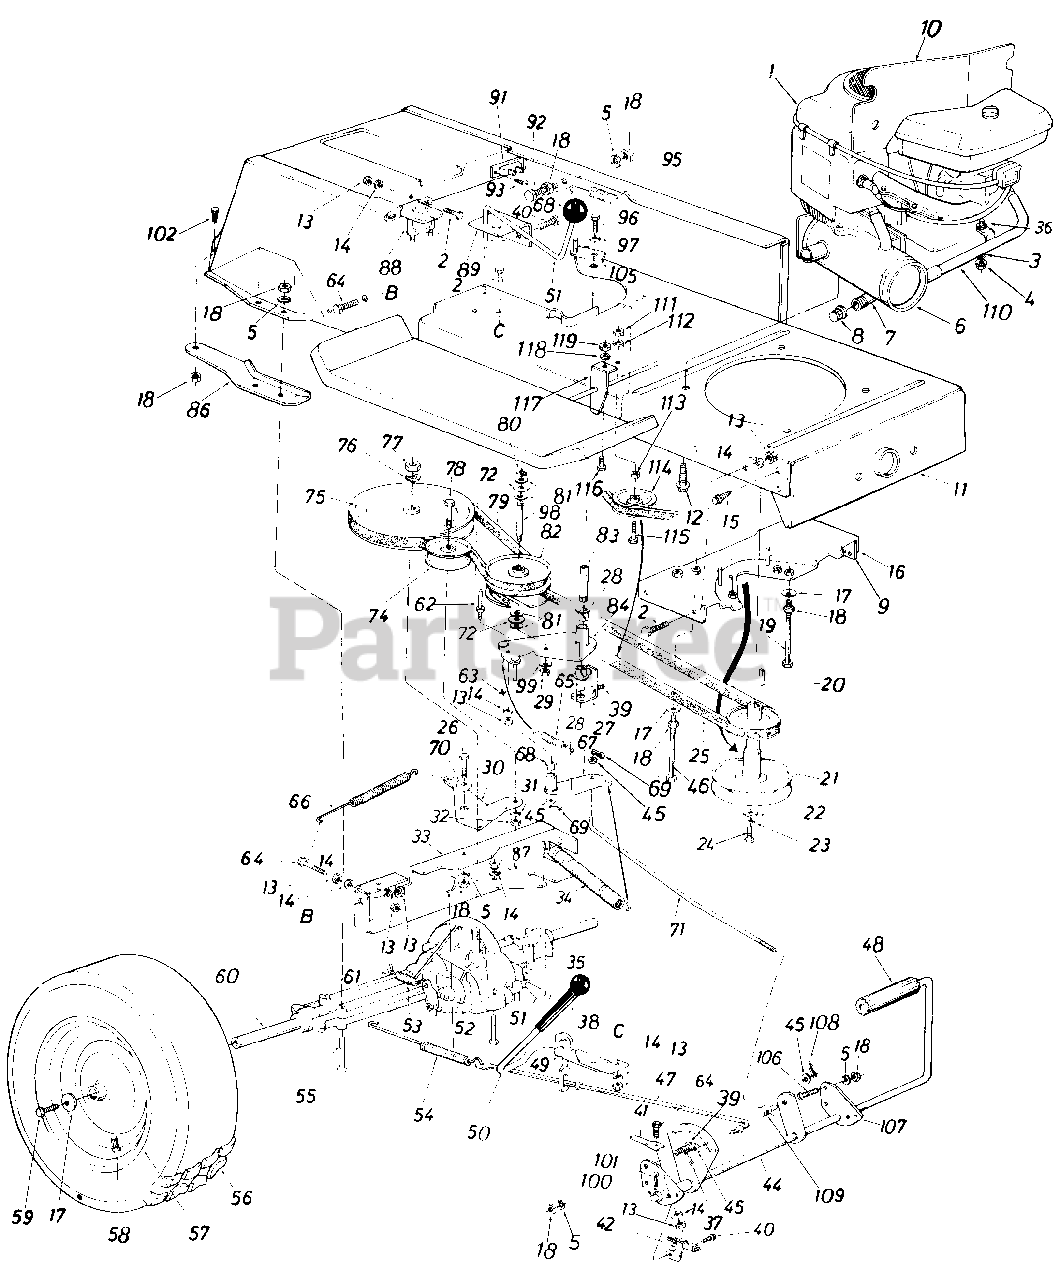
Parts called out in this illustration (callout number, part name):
1	Engine
2	Hex Bolt 1/4-20 x .62" Lg.
3	Special L-Wash. 5/16" I.D.
4	Hex Nut 5/16-18 Thd.
5	L-Wash. 5/16" I.D.
6	Exhaust Muffler
7	Pipe Nipple
8	Cap Oil Drain
9	Brake Cable Brkt.
10	Heat Shield
11	Lower Frame Ass'y.
12	Hex Wash. Hd. TT-Tap Scr. 3/8-16 x 1.25" Lg.
13	Hex Nut 1/4-20 Thd.*
14	L-Wash. 1/4" I.D.
15	Hex Wash. Hd. AB-Tap Scr. 5/16" x .75" Lg.
16	Belt Guard Brkt. Ass'y.
17	Bell-Wash. .345" I.D. x .88"
18	Hex Nut 5/16-18 Thd.
19	Hex Bolt 5/16-18 x 4.00"
20	Sq. Key 1/4" x 1/4" x 2.00"
21	Engine Pulley
22	Fl-Wash. 7/16" I.D. x 1.25"
23	L-Wash. 7/16" I.D.
24	Hex Bolt 7/16-20 x 1.50" Lg.
25	Variable-Speed Belt .715 x 53" Lg.
26	Hex Bolt 5/16-18 x .75" Lg.
27	Bearing Shaft Bracket
28	Flanged Nyliner Brg. 5/8" I.D. x .88" Lg.
29	Hex Nut 3/8-24 Thd.
30	Idler Bracket
31	L-Wash. 3/8" I.D.
32	Hex Nut 3/8-24 Thd.
33	Transaxle Support Brkt.
34	Ext. Spring .94" O.D. x 6.7
35	Cotter Pin 118" Dia. x 1.0"
36	Fl-Wash. .34" I.D. x .62" O.D. x .033
37	Cotter Pin 3/32" Dia. x 1.0"
38	Grip-Black
39	Truss Mach. Scr. 5/16-18 x .75" Lg.
40	Hex Wash. Hd. Self-Tap Scr. 1/4-20 x .50" Lg.
41	Switch Actuator
42	Safety Switch
44	Clutch & Brake Pedal Assy.
45	Fl-Wash.
46	Hex Bolt 5/16-18 x 4.5"
47	Brake Rod
48	Foot Pad
49	Brake Lever Bracket
50	Hill Holder Brake Handle
51	Shift Lever Ass'y.
52	Hex Bolt 1/4-28 x 1.75" Lg.
53	Ext. Spring .38" O.D. x 2.5"
54	Ext. Spring .59" O.D. x 7.08"
55	Hex Bolt 5/16-18 x 2.50"
56	Wheel Ass'y. Comp.
57	Wheel Rim Only
58	Air Valve
59	Hex Bolt 5/16-24 x .75" Lg.
60	Transaxle Complete
61	Brake Return Spring Anchor
62	Belt Guard Pin 1/4-20 Thd.
63	Cap Speed Nut 1/4" Dia.
64	Hex Bolt 1/4-20 x 1.0" Lg.
65	Ext. Spring .50" Dia.
66	Ext. Spring .56" O.D. x 5.96"
67	Variable Speed Torque Brkt. Ass'y.
68	Flanged Bearing
69	Cotter Pin 3/32" Dia.
70	Shoulder Spacer .500" Dia. x.27" Lg.
71	Speed Control Link
72	Truss Bearing .56 Dia. x 1 .25 "
74	Fl-Idler Pulley 3.25" x 1.0"
75	11/16" "V"-Pulley 8.0" O.D. x .501" I.D.
76	L-Wash. 1/2" I.D.
77	Hex Jam Nut 1/2-20 Thd.
78	Hex Bolt 3/8-24 x 1.50" Lg.
79	Variable Speed Belt .715 x 44" Lg.
80	Snap Ring .56" Dia.
81	Fl-Wash.
82	Variable Speed Pulley Ass'y. 5" O.D.
83	Bearing Shaft
84	Variable Speed Brkt. Assy.
86	Transaxle Support Brkt.-R.H.
87	Hex Nut 1/4-28 Thd.
88	Solenoid
89	Shift Lever Bracket
91	Circuit Breaker
92	Hex Bolt 5/16-18 x 1.25" Lg.
93	Truss Hd. Phil. Scr. #10 x 1/2" Lg.
95	Ext. Spring .99" O.D. x 11.0"
96	Hex Bolt 3/8-24 x .75" Lg.
97	Bell-Wash. .38" I.D. x .88"
98	Shaft .56" Dia. x 3.875" Lg.
99	Bell-Wash. .39" I.D. x 1.12"
100	Fl-Wash.
101	Cotter Pin
102	Hex Wash. Hd. Scr. 5/16-18 x.62" Lg.
105	Belt Guard
106	Truss Mach. Scr. 5/16-18 x .75" Lg.
107	Pedal Bracket
108	Hairpin Cotter 1/8" Dia.
109	Ferrule
110	Inlet Tube Ass'y.
111	Hex Nut 3/8"-16 Thd.*
112	L-Wash. 3/8" I.D.*
113	Fl-Wash. .390" I.D. x 1.12" O.D. x .187
114	Fl-Idler w/Flanges 2.750
115	Hex Bolt 3/8-16 x 2.00" Lg.*
116	Hex Bolt 1/4-20 x .62" Lg.*
117	Spring Hanger Bracket
118	L-Wash.1/4" I.D.*
119	Hex Nut 1/4-20 Thd.*
